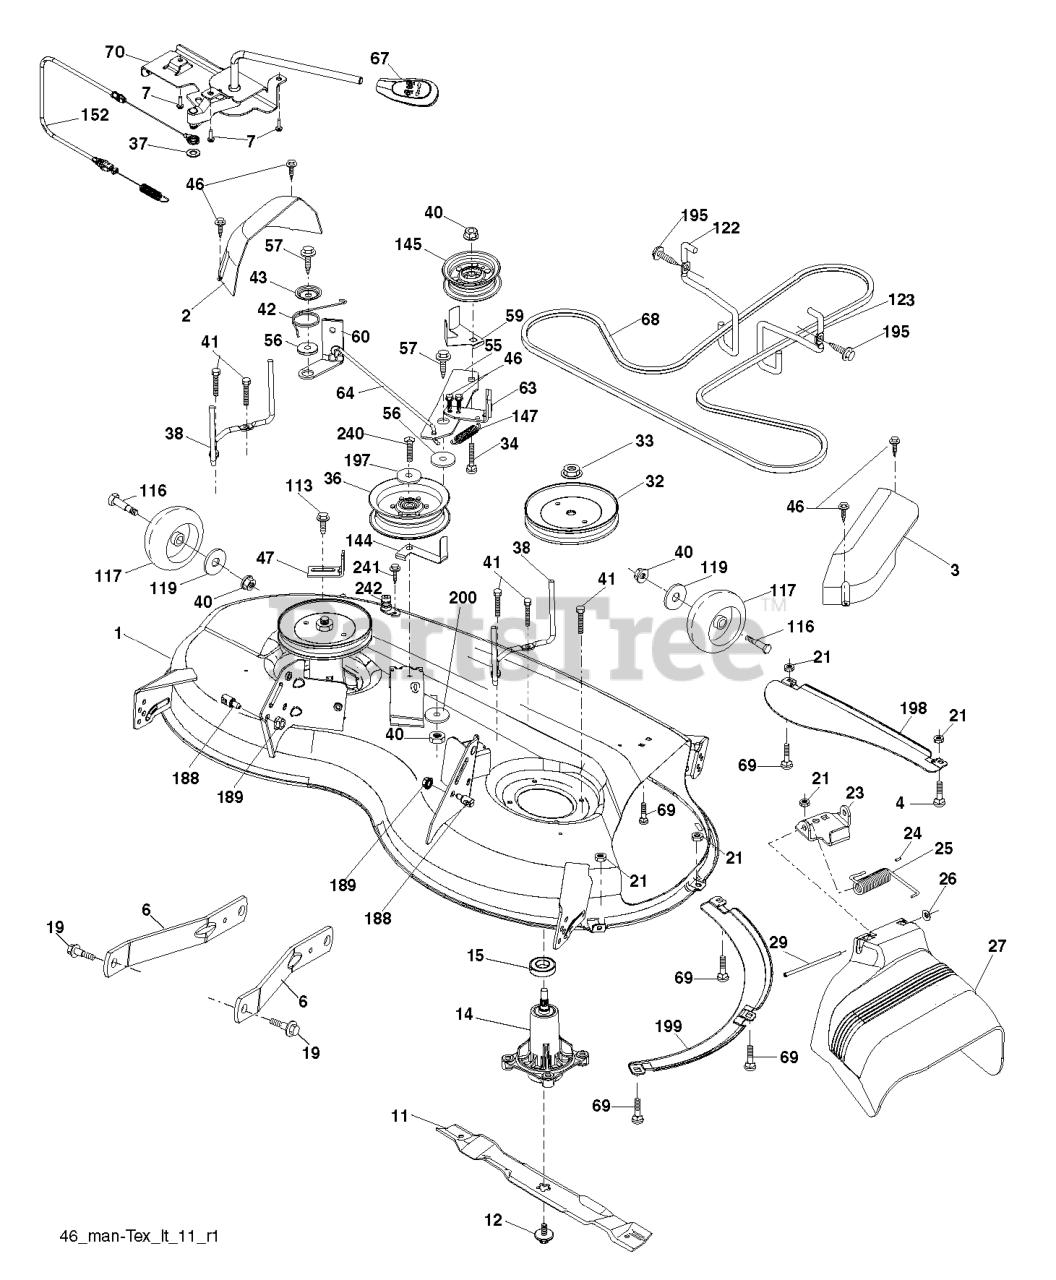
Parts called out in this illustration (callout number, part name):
1	RP DECK.WELDMENT.46"(2GA.WHL)
2	COVER.MANDREL.RH.46"
3	COVER.MANDREL.LH.46"
4	HCS 5/16C X 3/4
6	ARM.SUSPENSION.MOWER.R
11	BLADE.MOWER.46".HI.LIFT
12	SCREW.SEMS.7/16-20X1.HEX.HEAD
14	KIT.MANDREL.NONGREASE.TALL
15	BEARING
19	BOLT.SHOULDER
23	BRKT.DEFLECTOR.38"2005+
24	CAP-SLEEVE LT
25	SPRING.TORSION.DEFLECT
26	NUT PUSH M
27	SHIELD.DEFLECTOR.MOWER.46"BLAC
32	PULLEY.MANDREL.5.438.P
34	GSPW Bolts
36	PULLEY.IDLER.2006
37	WASHER PLAIN WASHER 3/8 X 0.08
38	KEEPER.BLT.PNT.MNDRL.PULL.6.25
40	NUT LOCK FLG 3/8-16 UNC
41	BOLT.HEX.WASHR.HED.313-18X1.19
42	SPRING.TORSION.BRAKE
43	SRPING.TORSION.RETAINE
46	SCREW.1/4-20X5/8
47	BRKT.CLUTCH.CABLE
56	SPACER.RETAINER
57	SCREW 3/8-16X1
59	GUARD, BELT
60	ARM BRAKE MOWER RH 38"
63	ARM.BRAKE.ZINC
64	LINKAGE.ASM.BRAKE.CLEAR.ZINC
67	HANDLE.CLUTCH.CABLE.LT
68	V-BELT
70	CLUTCH.ASM.MANUAL.YT.PREDATORQ
113	BOLT.5/16HEX.WHS.HD
117	WHEEL.GAUGE.RALLY
122	KEEPER BELT ENGINE LH
123	KEEPER BELT RH
144	KEEPER.BELT.MOWER
145	PULLEY.IDLER.48"PRIMARY
147	SPRING RETURN
152	CABLE.MECHANICAL.CLUTCH
188	STUD.W/"D"ANTI-ROTATION
195	SCREW, 3/8-16X3/4
198	BAFFLE CENTER FRONT
199	BAFFLE FRONT RH
200	WASHER.13/32 X 1 X 1/2.11GUARD
241	SCREW.TT.#10-32X.5.3/8.FLANGE
242	PORT.WASHOUT
